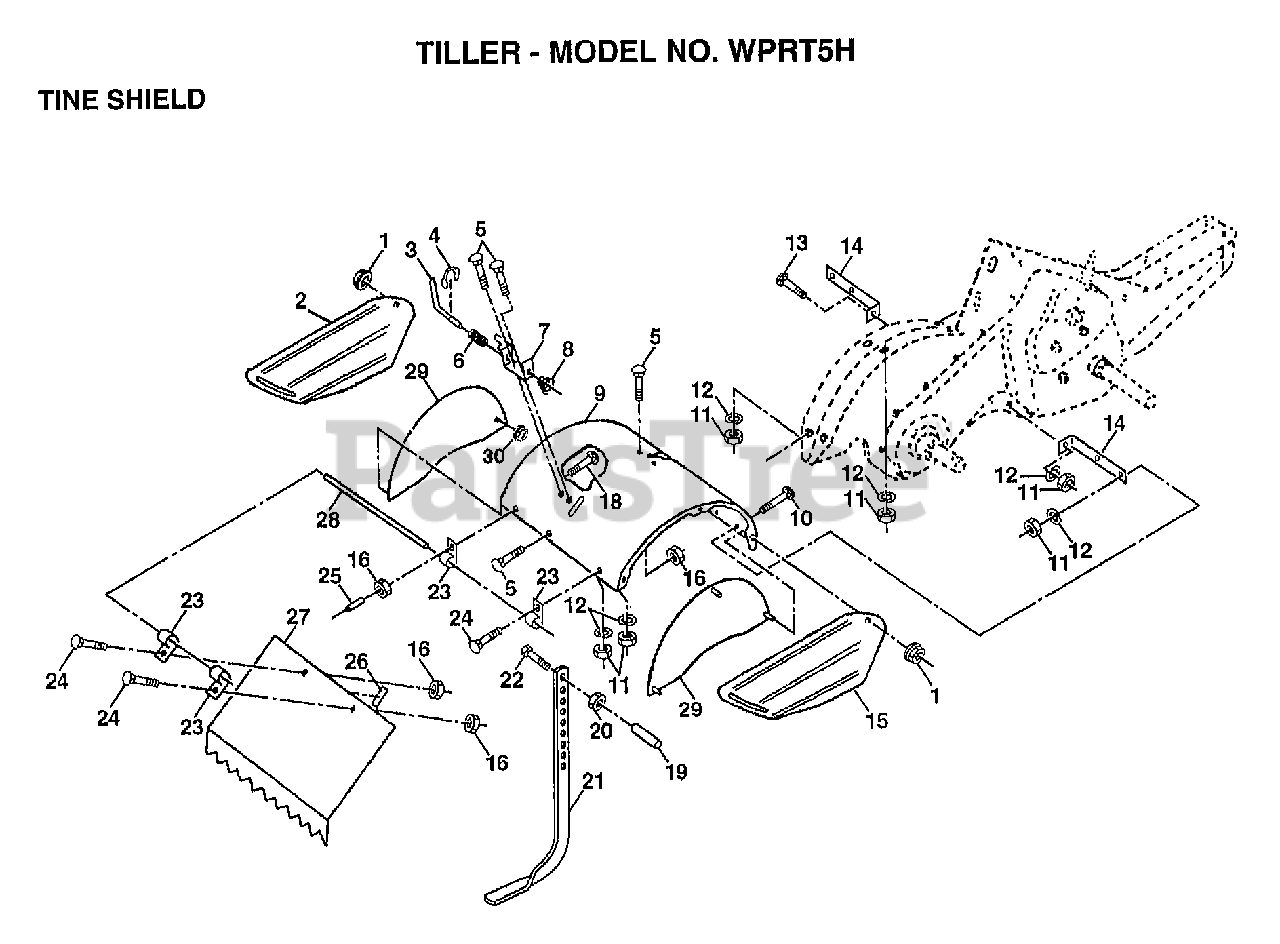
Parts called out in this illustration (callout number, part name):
1	NUT
2	"SHIELD,SIDE,O.LH"
3	STAKE PIN TI
4	KLIP RING TI
5	BOLT
6	SPRING TI
7	LATCH BRACKET TI
8	SPRING CRT
9	TINE SHIELD
10	BOLT
11	NUT.HEX.5/16-18
12	LOCKWASHER
13	BOLT
14	"BRACKET,SHIELD"
15	SHIELD SIDE O.RH
16	NUT
18	BOLT
19	GRIP CRT
20	NUT.HEX.3/8-16UNC
22	BOLT
23	HINGE CRT
24	BOLT
25	VINYL CAP TI
26	PAD IDLER TI
27	LEVELING SHIELD
28	PIN HINGE
29	SIDE SHIELD
30	LOCKNUT TI
